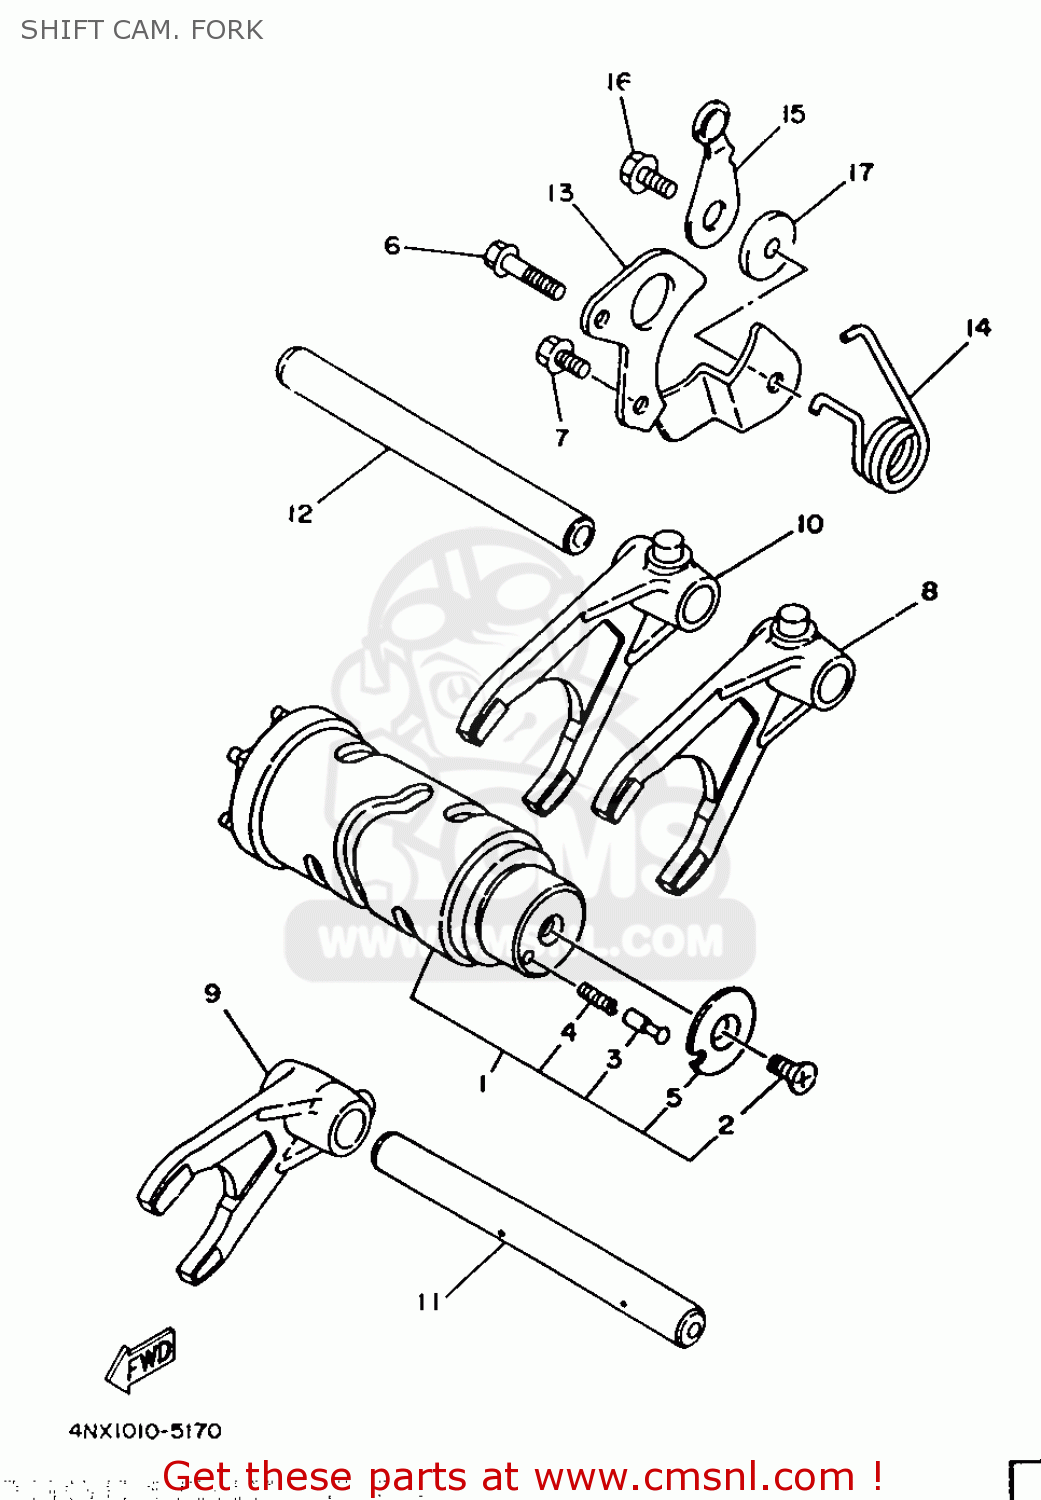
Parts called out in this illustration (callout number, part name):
01	SHIFT CAM ASSY
02	SCREW, FLAT
03	POINT, NEUTRAL
04	SPRING COMPRESSION278185450000
05	PLATE, SIDE 2
06	BOLT, FLANGE
07	BOLT, WASHER BASED(1AA)
08	FORK, SHIFT 1
09	FORK, SHIFT 2
10	FORK, SHIFT 3
11	BAR, SHIFT FORK GUIDE 1
12	BAR, SHIFT FORK GUIDE 2
13	STOPPER, SHIFT BAR
14	SPRING, TORSION(4NX)
15	STOPPER LEVER ASSY
16	BOLT, WASHER BASED(85F)
17	SPACER
